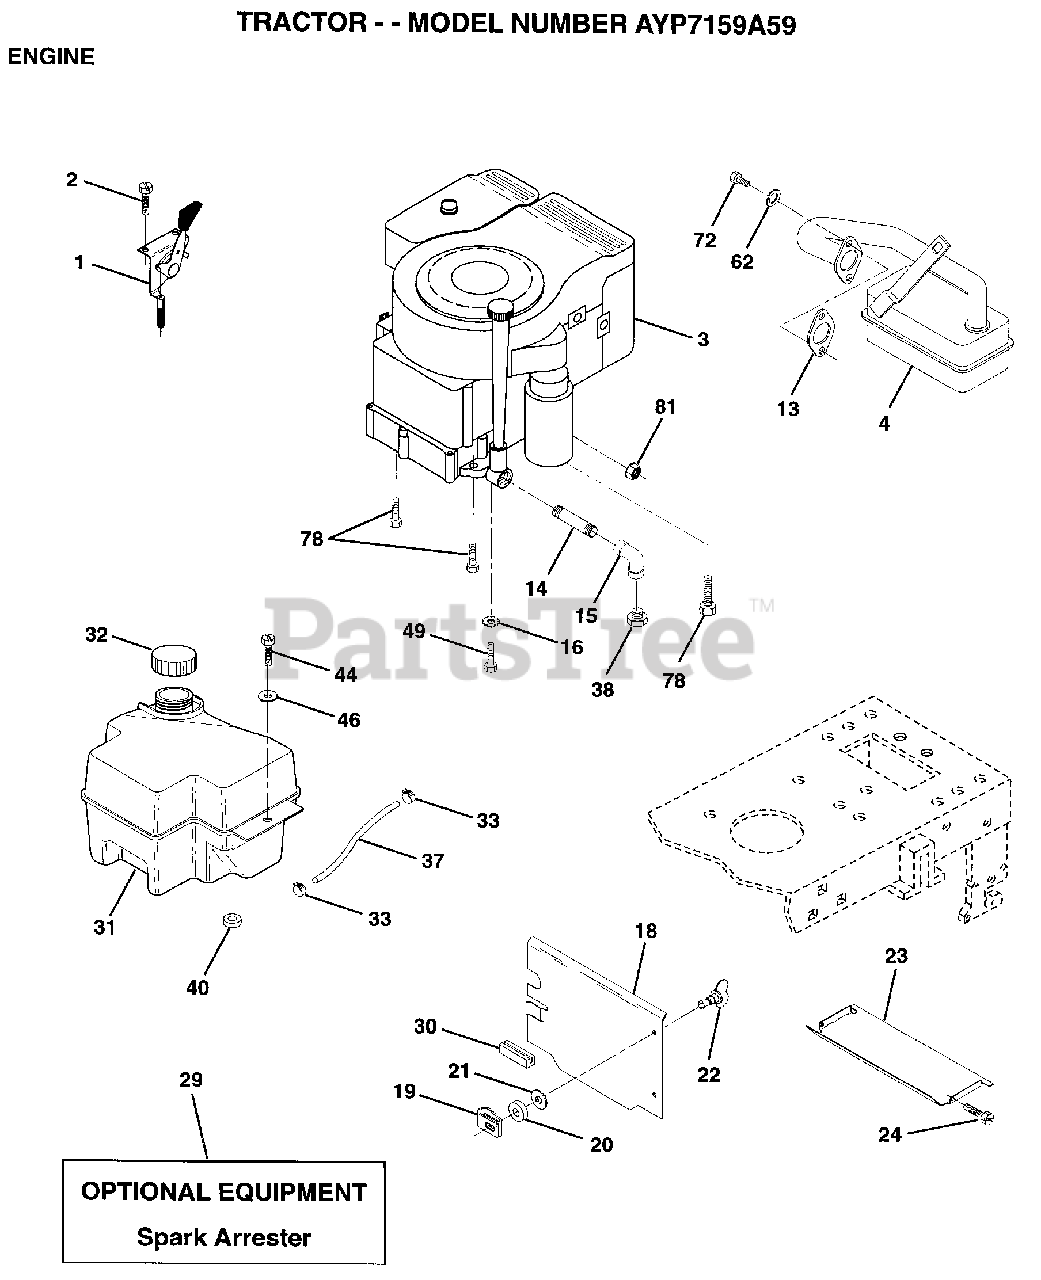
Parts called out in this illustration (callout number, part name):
1	CONTROL THROTTLE
2	SCREW LT
4	MUFFLER
14	PIPE NIPPLE
15	ELBOW
16	LOCKWASHER
18	SHIELD HEAT
19	RECEPTACLE LT
20	RETAINER LT
21	WASHER
22	STUD.1/4.TURN
23	HEAT SHIELD
24	SCREW
32	CAP ASM FUEL
33	HOSE CLAMP
37	LINE FUEL
44	SCREW HEX CRT
46	WASHER
49	SCREW GTV
62	LOCKWASHER
72	SCREW
78	SCREW
81	NUT
